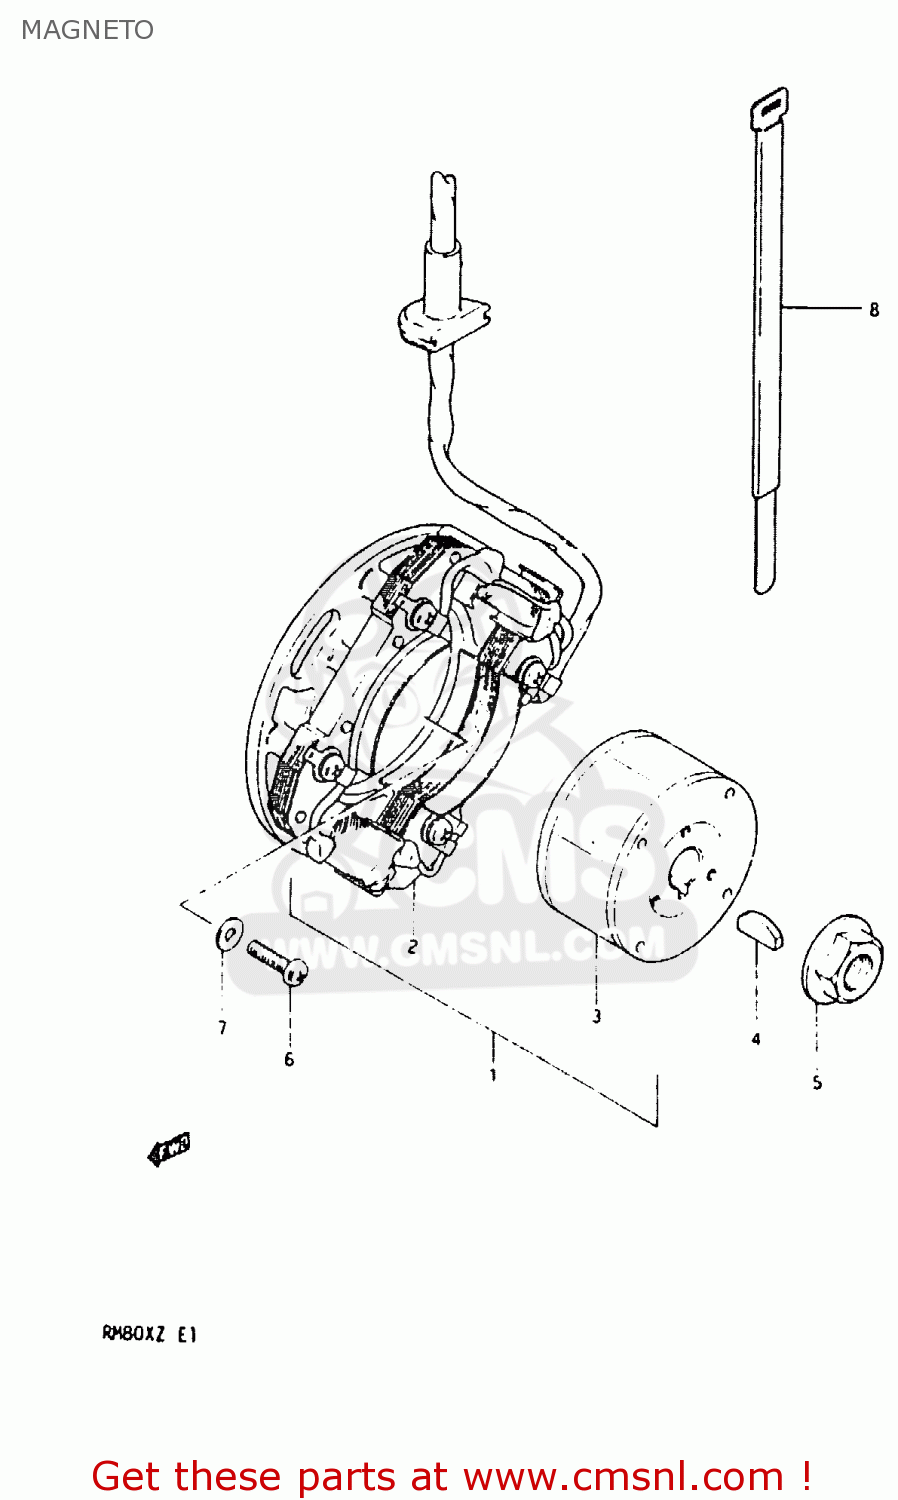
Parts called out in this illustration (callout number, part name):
1	MAGNETO ASSEMBLY
2	STATOR ASSEMBLY
3	ROTOR ASSEMBLY
4	KEY 4MM
5	NUT
6	SCREW
7	WASHER
8	CLAMP
